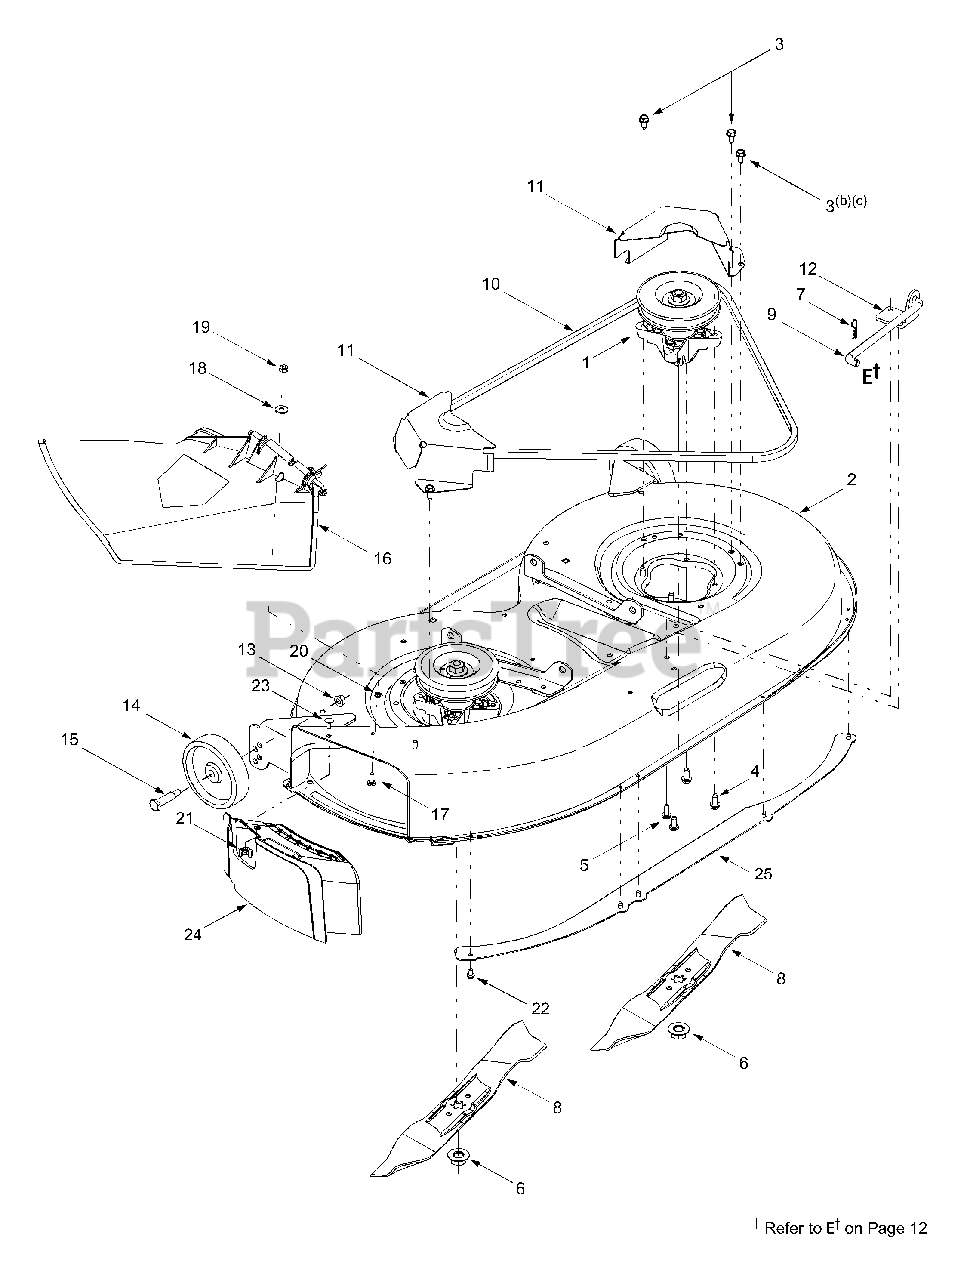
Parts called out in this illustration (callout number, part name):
1	Spindle Assembly
4	Screw, 5/16-18 x .75
5	Self-tapping Screw, 5/16-18 x .75
6	Hex Flange Nut, 5/8-18
7	Internal Cotter Pin, .080 x 1.56
8	Blade, 21.23"
9	Deck Hanger Link/Anti-sway Rod
10	Deck Belt
13	Flange Lock Nut, 3/8-16
14	Deck Wheel, 5 x 1.38
15	Shoulder Screw, .498 x 1.53
16	Discharge Chute Assembly
17	Hex Cap Screw:1/4-20 x .620
18	Bell Washer, .265 x .75 x .062
19	Hex Nut, 1/4-20
20	Push Nut, 1/4
21	Wing Nut, 1/4-20
22	Self-tapping Screw, 1/4-20 x .5
23	Carriage Screw, , 1/4-20 x .62
24	Mulch Plug
